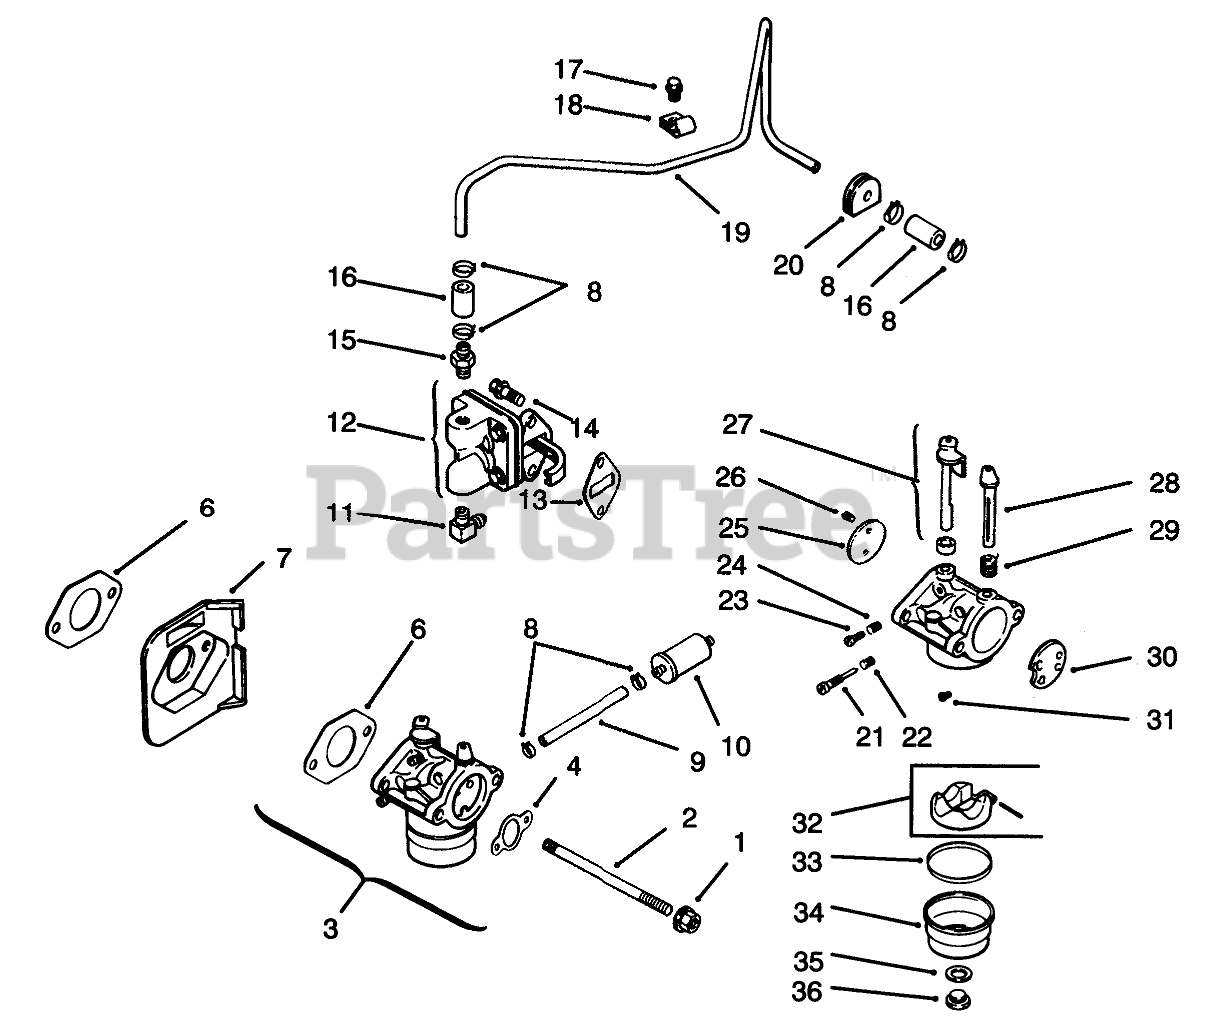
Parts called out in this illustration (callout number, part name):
1	Nut M6x1.0 (Only On: 72042, 72043, 72062, 72063)
2	Stud M6x1.0x110 (Only On: 72042, 72043, 72062, 72063)
3	Kit-Carb INCL 4/6/21-36 (Only On: 72042, 72043, 72062, 72063)
4	Gasket-Air Cleaner (Only On: 72042, 72043, 72062, 72063)
6	Gasket-Carburetor (Only On: 72042, 72043, 72062, 72063)
7	Deflector-Heat (Only On: 72042, 72043, 72062, 72063)
8	Clamp-Hose (Only On: 72042, 72043, 72062, 72063)
9	Line-Fuel 3" (Only On: 72042, 72043, 72062, 72063)
10	Filter-Fuel (Only On: 72042, 72043, 72062, 72063)
11	Connector-90 DEG (Only On: 72042, 72043, 72062, 72063)
12	Kit-Pump INCL 13-14 (Only On: 72042, 72043, 72062, 72063)
13	Gasket-Fuel Pump (Only On: 72042, 72043, 72062, 72063)
14	Screw M6x1.0x20 (Only On: 72042, 72043, 72062, 72063)
15	Connector-Straight (Only On: 72042, 72043, 72062, 72063)
16	Line-Fuel 1.25 Inch (Only On: 72042, 72043, 72062, 72063)
17	Screw M5x0.8x10 (Only On: 72042, 72043, 72062, 72063)
18	Clamp-Fuel Line (Only On: 72042, 72043, 72062, 72063)
19	Line-Fuel (Only On: 72042, 72043, 72062, 72063)
20	Grommet (Only On: 72042, 72043, 72062, 72063)
21	Needle-Idle Fuel Adjust (Only On: 72042, 72043, 72062, 72063)
22	Spring-Idle Fuel (Only On: 72042, 72043, 72062, 72063)
23	Screw-Idle Speed Adjust (Only On: 72042, 72043, 72062, 72063)
24	Spring-Idle Fuel (Only On: 72042, 72043, 72062, 72063)
25	Plate-Throttle (Only On: 72042, 72043, 72062, 72063)
26	Screw-Throttle Plate (Only On: 72042, 72043, 72062, 72063)
27	Shaft-W/Lever & Seal (Only On: 72042, 72043, 72062, 72063)
28	Shaft-Choke (Only On: 72042, 72043, 72062, 72063)
29	Spring-Choke Return (Only On: 72042, 72043, 72062, 72063)
30	Plate-Choke (Only On: 72042, 72043, 72062, 72063)
31	Jet-Main (Only On: 72042, 72043, 72062, 72063)
32	Kit-Float (Only On: 72042, 72043, 72062, 72063)
33	Gasket-Bowl (Only On: 72042, 72043, 72062, 72063)
34	Bowl-Fuel (Only On: 72042, 72043, 72062, 72063)
35	Gasket-Bowl Screw (Only On: 72042, 72043, 72062, 72063)
36	Screw-Fuel Bowl (Only On: 72042, 72043, 72062, 72063)
